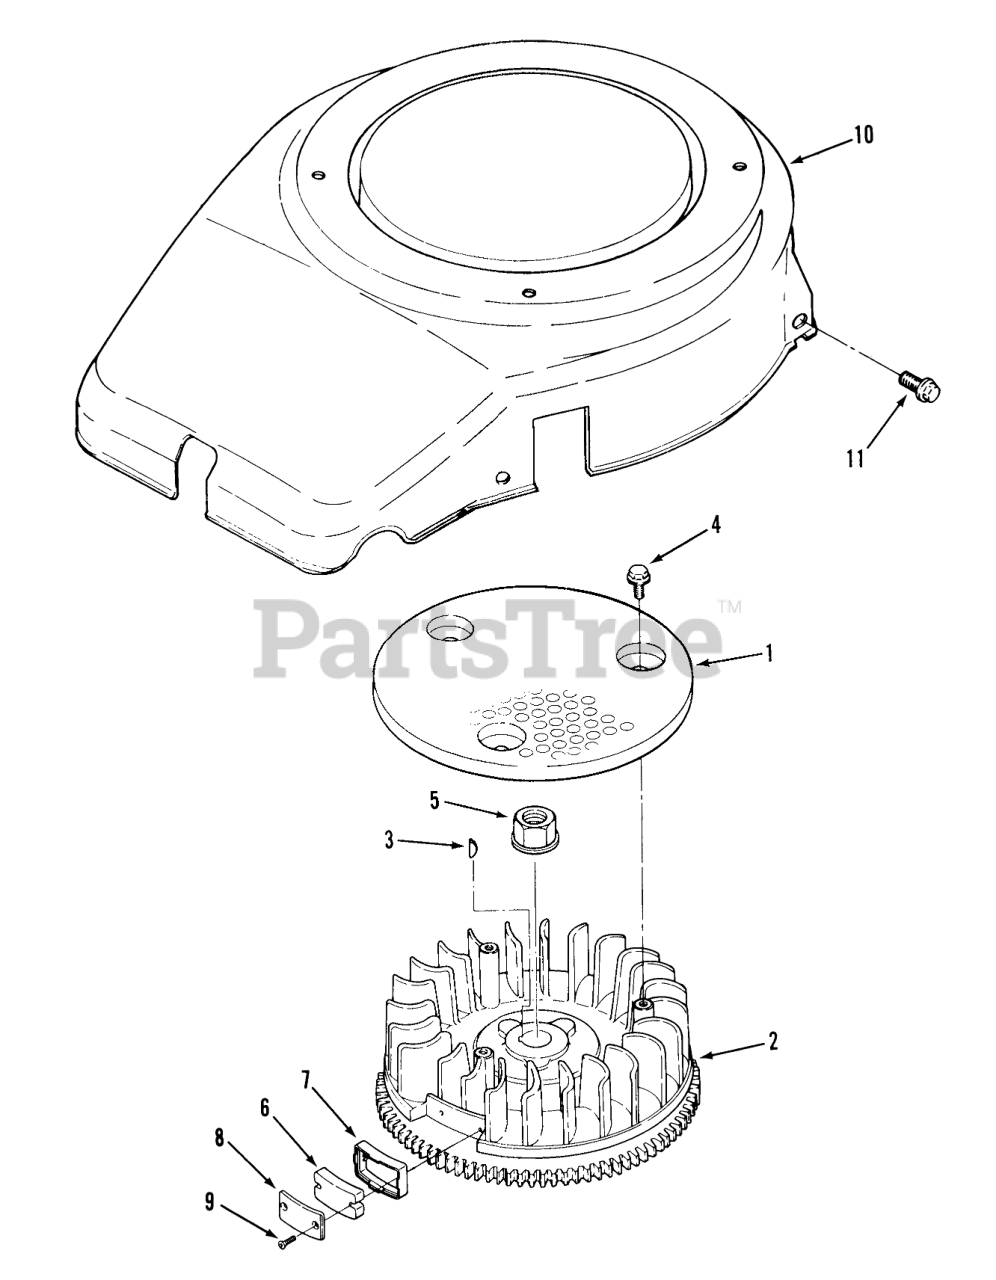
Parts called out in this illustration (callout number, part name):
1	Screen
2	WHL-ASS'Y BLOWER
4	Screw-Hex Hd.
5	NUT-FLANGE M18
6	Magnet
7	Holder
8	Cover
9	Screw
10	Blower Housing
11	BOLT-HHF M6 X 12MM
